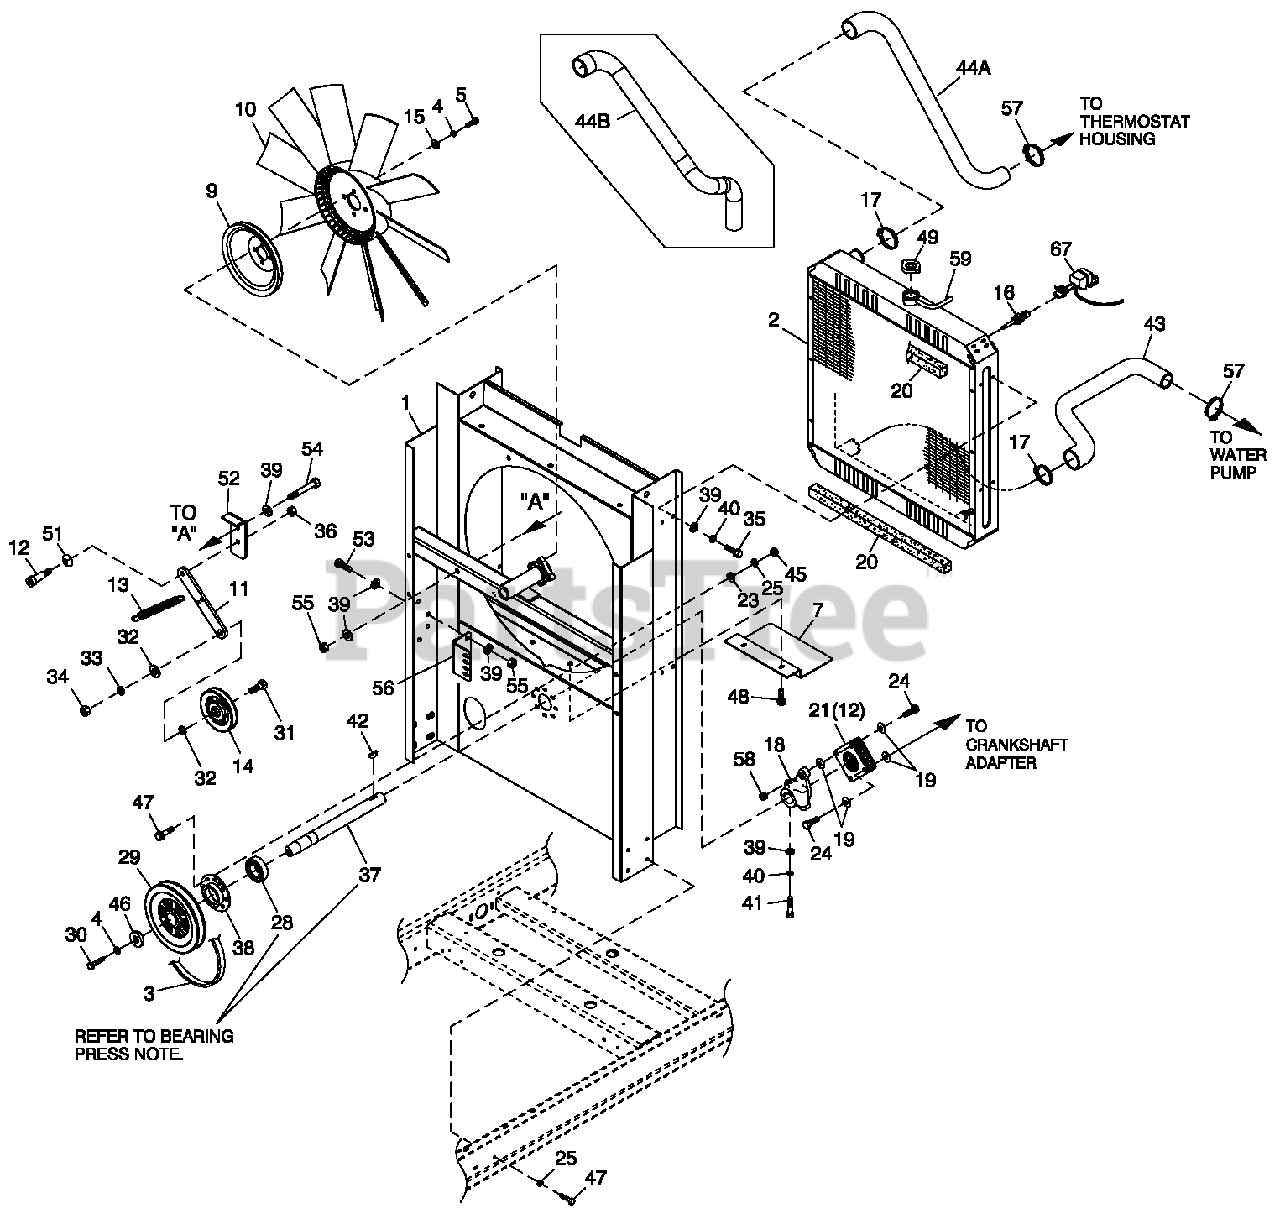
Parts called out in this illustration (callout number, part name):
1	WELDMENT RADIATOR SUPPORT C2
2	RADIATOR 598 X 568 X 49 CPL RH
3	V-BELT A58 (60IN O.C.) DDC S60
4	WASHER LOCK M10
5	SCREW HHC M10-1.5 X 30 G10.9
6	HOSE 2"ID X 3.0"LG
7	SHIELD RADIATOR C4
8	TANK COOLANT RECOVERY
9	PULLEY FAN V-GROOVE 9"
10	FAN COOL 22" DIA 10 BLADE LH
11	FLAT TENSIONER ARM
12	SHOULDER BOLT 3/8 X 1/2"
13	SPRING TENSION CPL
14	PULLEY V-BELT 4" FLANGED
15	WASHER FLAT 3/8-M10 ZINC
16	PROBE COOLANT LEVEL 3/8NPTF
17	CLAMP HOSE #28 1.32-2.25
18	HUB FLEX PLATE
19	WASHER FLEX (THIN)
20	TAPE FOAM 1 X 1 (26.75" LG)
21	DISK FLEX
22	BRACKET COOLANT TANK
23	WASHER FLAT 1/4-M6 ZINC
24	SCREW HHC 5/16-24 X 1.124
25	WASHER LOCK M6-1/4
26	TANK COOLANT RECOVERY
27	CLAMP HOSE BAND 1/4
28	BEARING #6205 2NSE C3 E SRI2 S
29	PULLEY 7.5" DIA MACHINED
30	SCREW HHC M10-1.5 X 30 G8.8
31	SCREW HHC 1/2-13 X 2" G8
32	WASHER FLAT 1/2 ZINC
33	WASHER LOCK 1/2
34	NUT HEX 1/2-13 STEEL
35	SCREW HHFC M8-1.25 X 20 W/M6
36	NUT HEX LOCK 5/16-18 NY INS SS
37	SHAFT FAN DRIVE
38	RETAINER BEARING
39	WASHER FLAT 5/16-M8 ZINC
40	WASHER LOCK M8-5/16
41	SCREW HHC M8-1.25 X 45 C8.8
42	KEY WOODRUFF 4 X 19D
43	HOSE LOWER RADIATOR G2
44A	HOSE UPPER RADIATOR G2
44B	HOSE UPPER RADIATOR G2
45	NUT HEX M6 X 1.0 G8 YEL CHR
46	SPACER .5 X 1.5 X .25 STL/ZINC
47	SCREW HHFC M6-1.0 X 20 G8.8
48	SCREW THF M6-1 X 16 N WA Z/JS
49	CAP RADIATOR 13 PSI
50	BRACKET COOLANT TANK
51	WASHER BELLEVILLE .75X.38X.028
52	TENSIONER ARM SUPPORT BENT 90
53	SCREW HHC M8-1.25 X 20 C8.8
54	SCREW HHC M8-1.25 X 75 C8.8
55	NUT HEX LOCK M8-1.25 NY INS
56	BRACKET TENSIONER SPRING
57	CLAMP HOSE #24 B1.06-2.00
58	NUT HEX LOCK 5/16-24 NY INS
59	HOSE 9/32 ID (36" LG)
60	CAC 504W X 152H X 50D 2.4L G2
61	CLAMP CNST TENSION 1.75-2.625
62	HOSE 2"ID X 3.0"LG
63	TUBE CAC IN
64	TUBE CAC OUT G2 TURBO
65	SCREW THF M6-1 X 30 N WA DELTA
67	ASSY PCB LCL SENSOR (USE WITH I/N 16, P/N 0H1827 ONLY)
